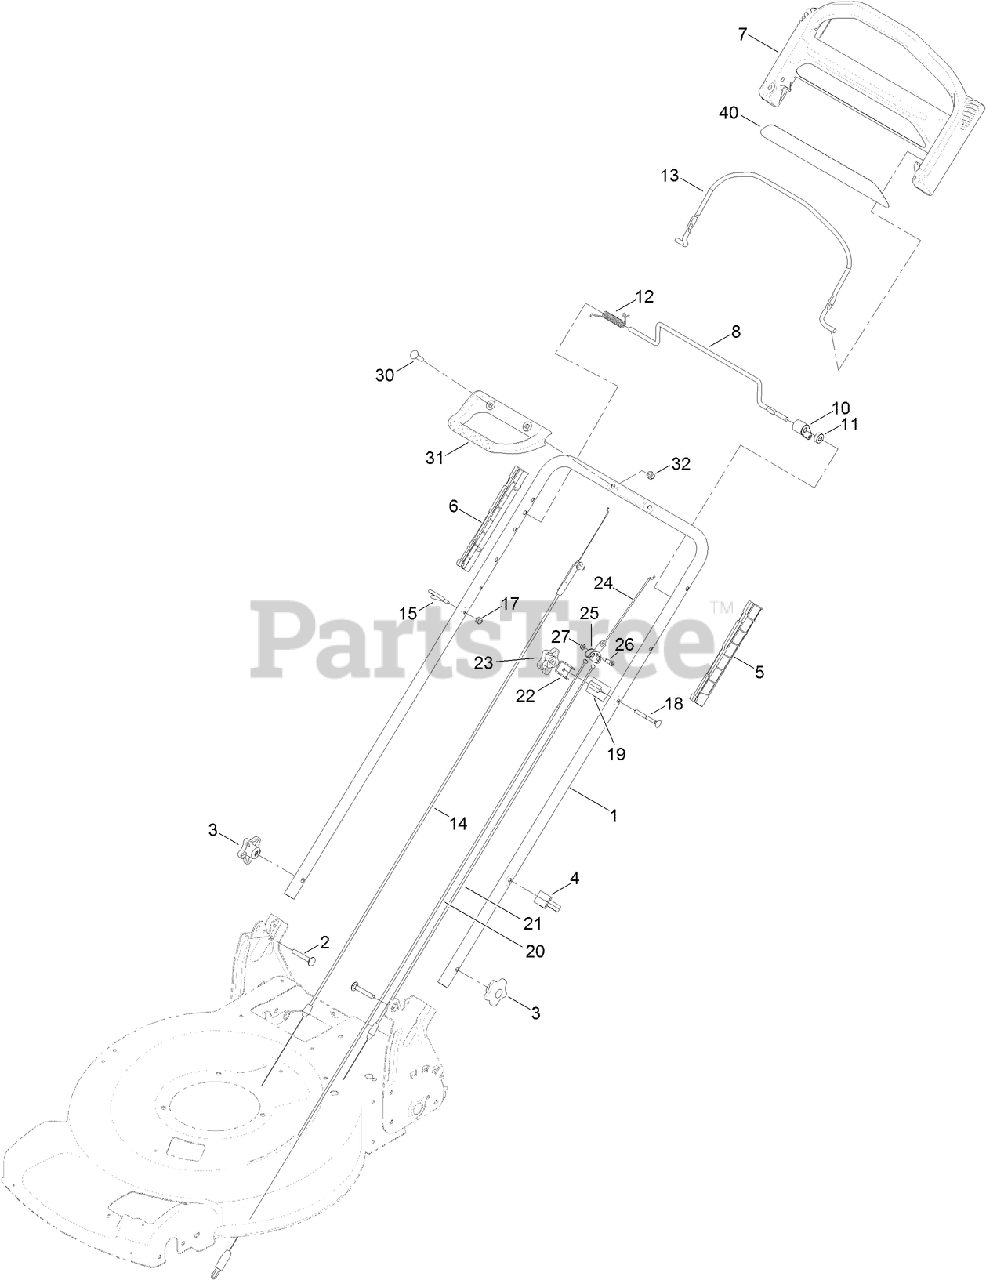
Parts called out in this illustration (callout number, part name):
2	BOLT-CARR
3	KNOB-HANDLE
4	GUIDE-CABLE
5	GUIDE-LH
6	GUIDE-RH
7	HANDLE-CONTROL
10	LEVER-TRACTION
11	SPACER
14	CABLE-BRAKE
15	GUIDE-ROPE
17	NUT-LOCK, NI
18	SCREW-HANDLE
19	MOUNT-CABLE, TRACTION
20	CABLE-TRACTION, FRONT
21	CABLE-TRACTION, REAR
23	KNOB-HANDLE, LOCKING
25	YOKE-CABLE
26	SCREW-SHOULDER
27	NUT-LOCK, NI
30	BOLT-CARRIAGE
31	HANDLE-ASSIST, TRACTION
32	NUT-ACORN
40	DECAL-DRIVE, AUTOMATIC
